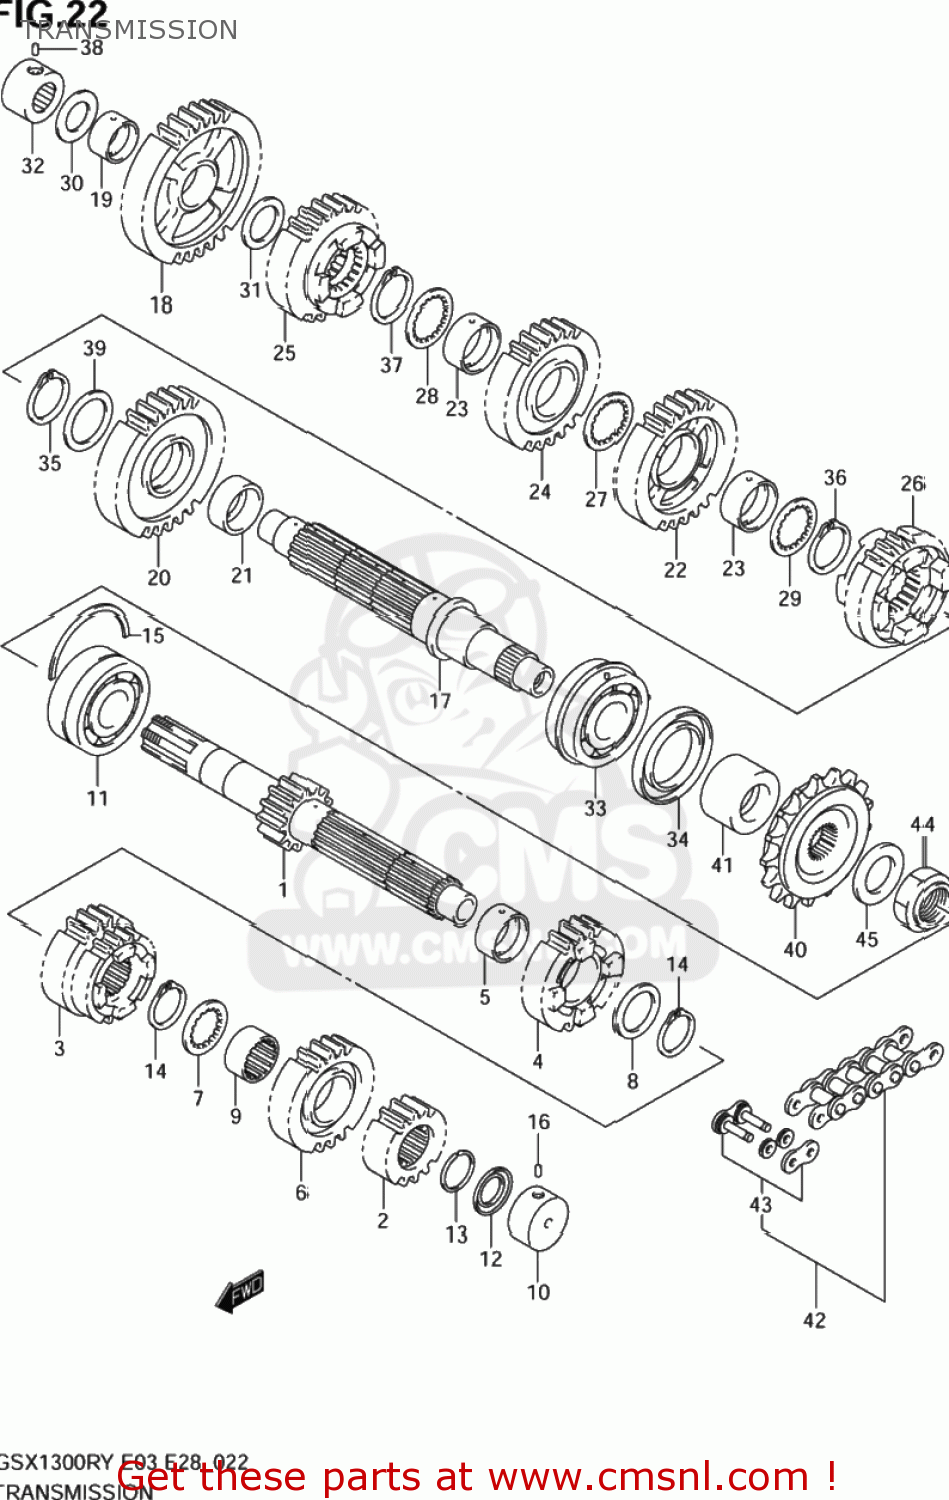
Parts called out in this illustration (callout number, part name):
1	SHAFT,COUNTER
2	GEAR,2ND DRIVE(NT:16)
3	GEAR,3RD & 4TH DRIVE
4	GEAR,5TH DRIVE(NT:22)
5	BUSH,5TH DRIVE GEAR
6	GEAR,6TH DRIVE
7	WASHER,LOCK
8	SHIM(27X36X2.5)
9	BUSH,6TH DRIVE GEAR
10	BEARING(20X34X17.5)
11	BEARING(25X62X25.4)
12	SEAL,OIL(20X31.2X2.7)
13	CIRCLIP
14	CIRCLIP
15	C RING
16	PIN
17	SHAFT,DRIVE
18	GEAR,1ST DRIVEN
19	BUSH,1ST DRIVEN GEAR
20	GEAR,2ND DRIVEN(NT:31)
21	BUSH,2ND DRIVEN GEAR
22	GEAR,3RD DRIVEN(NT:29)
23	BUSH,DRIVEN GEAR
24	GEAR,4TH DRIVEN(NT:27)
25	GEAR,5TH DRIVEN
26	GEAR,6TH DRIVEN
27	WASHER,LOCK
28	WASHER,LOCK
29	WASHER,LOCK
30	SHIM(20X34X1)
31	SHIM(24X34X1)
32	BEARING(20X34X20)
33	BEARING(30X62X23.8)
34	SEAL,OIL(42X62X7)
35	CIRCLIP
36	CIRCLIP
37	CIRCLIP
38	PIN
39	WASHER
40	SPROCKET,ENGINE(NT:17)
41	SPACER,ENGINE SPROCKET
42	CHAIN ASSEMBLY RKGB50GSVZ3
43	JOINT SET,DRIVE CHAIN
44	NUT
45	SHIM(25X40X1.5)
